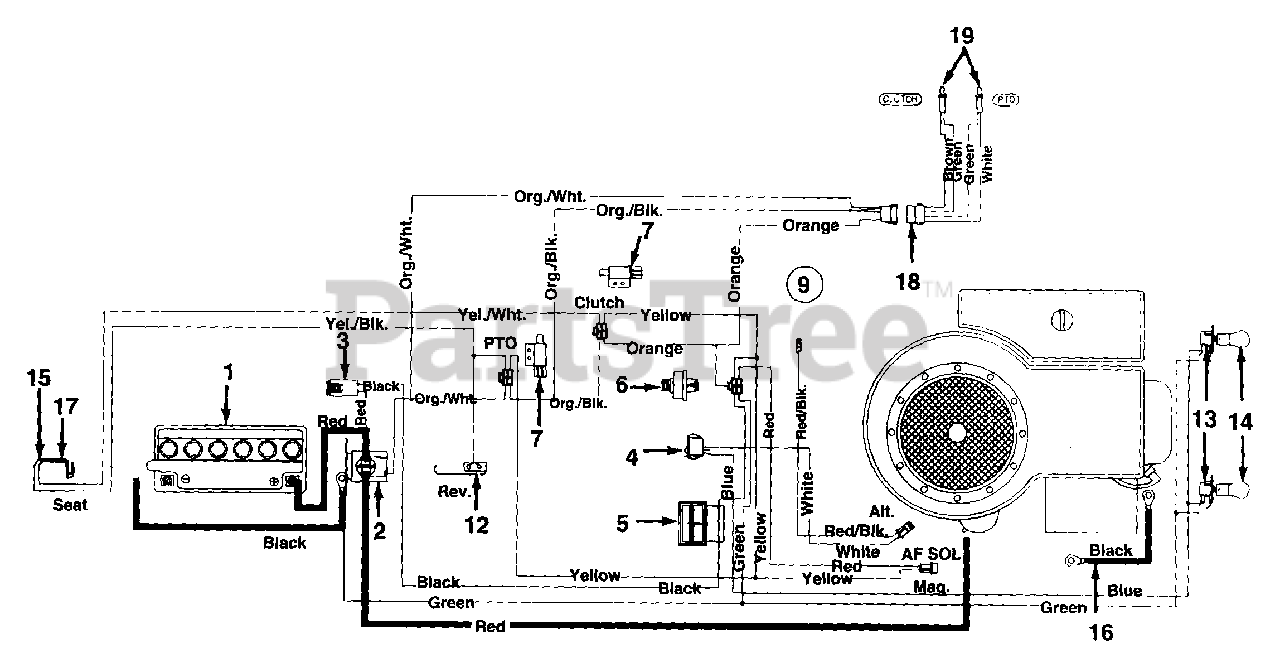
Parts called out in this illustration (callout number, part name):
1	Battery
2	Solenoid
3	Fuse 7.5 Amps
4	Light Switch
5	Ammeter
6	Ignition Switch
7	Safety Switch (Clutch)
9	Wire Harness w/Monitor
12	Safety Switch (Reverse)
13	Socket
14	Bulb (Headlight)
15	Safety Switch (Seat)
16	Ground Wire 7.5" Lg.
17	Safety Switch (Seat)
18	Monitor Harness
19	Monitor Bulb
